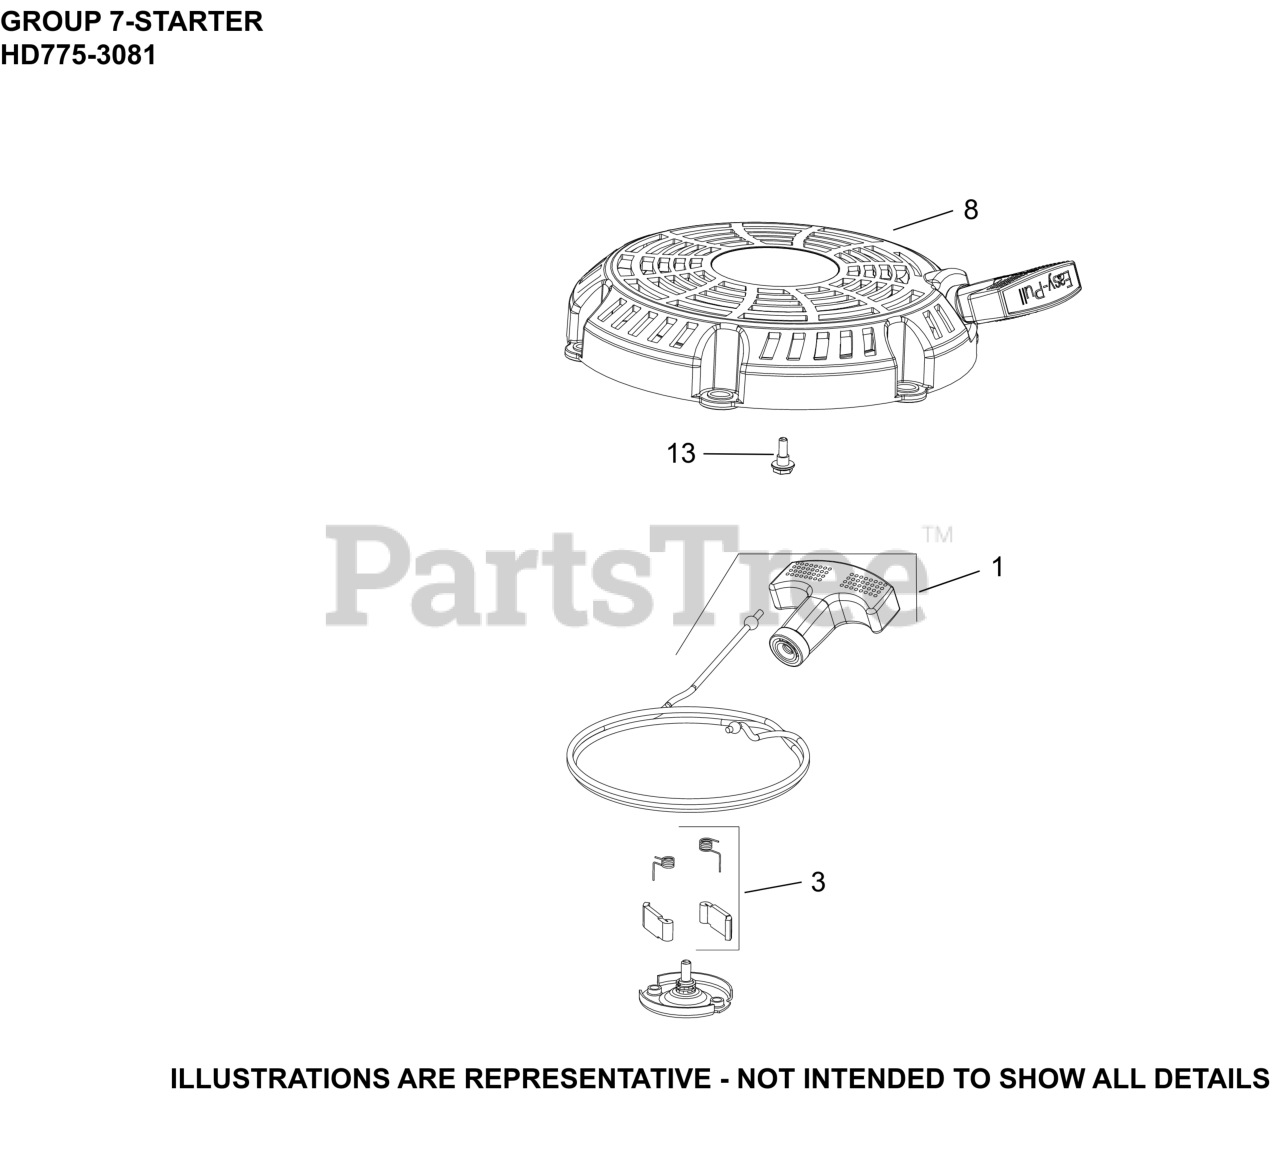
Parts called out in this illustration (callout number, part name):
1	KIT, STARTER ROPE W/HANDLE
3	KIT, PAWL REPAIR
8	STARTER ASSY-RETRACT
13	SCREW, SHOULDER (M5)
